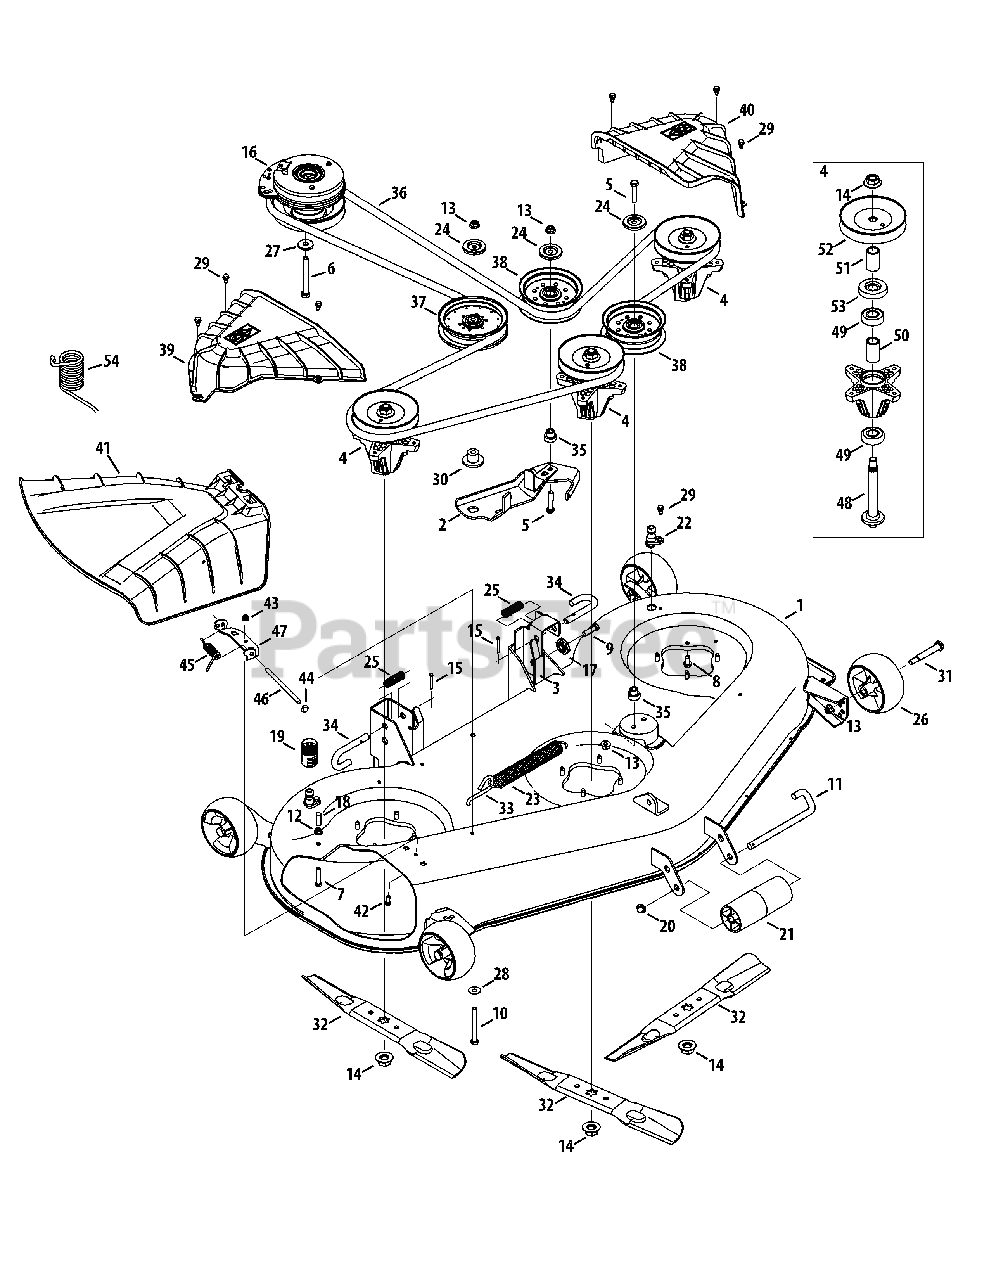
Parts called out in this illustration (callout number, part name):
1	54" Deck
2	Deck Idler Assembly
3	Deck Lift Bracket
4	Spindle Assembly
5	Hex Cap Screw, 3/8-16 x 1.75
6	Hex Cap Screw, 7/16-20 x 3.50
7	Hex Head Screw, 5/16-18 x 1.50
8	Hex Washer Screw, 5/16-18 x .750
9	Hex Flange Screw, 3/8-16
10	Hex Bolt 3/8-16 x 3.25"
11	Roller Pin, 1/2 x 7.31 Lg
12	Flange Lock Nut, 5/16-18
13	Flange Lock Nut, 3/8-16
14	Hex Flange Nut, 5/8-18
15	Cotter Pin, 5/32 x 1.25
16	Clutch, Electric PTO
17	Deck Adjustment Gear
18	Vinyl Cap, .29 x 1.00
19	Water Nozzle Adapter
20	Push Cap, 1/2
21	Front Roller
22	Deck Wash Nozzle
23	Extension Spring, 1.25 OD x 1.751
24	Pulley Cap
25	Compression Spring, .66 x 1.9
26	Deck Ball Wheel, 5.0
27	Flat Washer, .450 x 1.25 x .164
28	Flat Washer, .385 x 1.0 x .030
29	Shoulder Screw, 1/4-20 x 0.50
30	Shoulder Spacer
31	Shoulder Screw, .5 x 2.5 x 3/8-16
32	Blade, 18.67
33	Deck Spring Rod
34	Deck Hanger Rod
35	Shoulder Spacer
37	Idler Pulley, 5.00 Dia.
38	Pulley, Idler, 4.50" Dia.
39	Belt Cover, RH
40	Belt Cover, LH
41	Chute Deflector Assembly
42	Hex Cap Screw, 1/4-20 x .62
43	Nut, Flange Lock, 1/4-20, Nylon
44	Push Cap
45	Spring, Torsion, .440 ID x 1.75
46	Hinge Pin
48	Spindle Shaft, 6.11 Long
49	Ball Bearing
50	Spacer, .792 x 1.060 x 1.860
51	Spacer, .792 x 1.060 x 1.782
52	Deck Pulley
53	Bearing Shield
54	Torsion Spring, 1.323 ID x 2.83 LG
